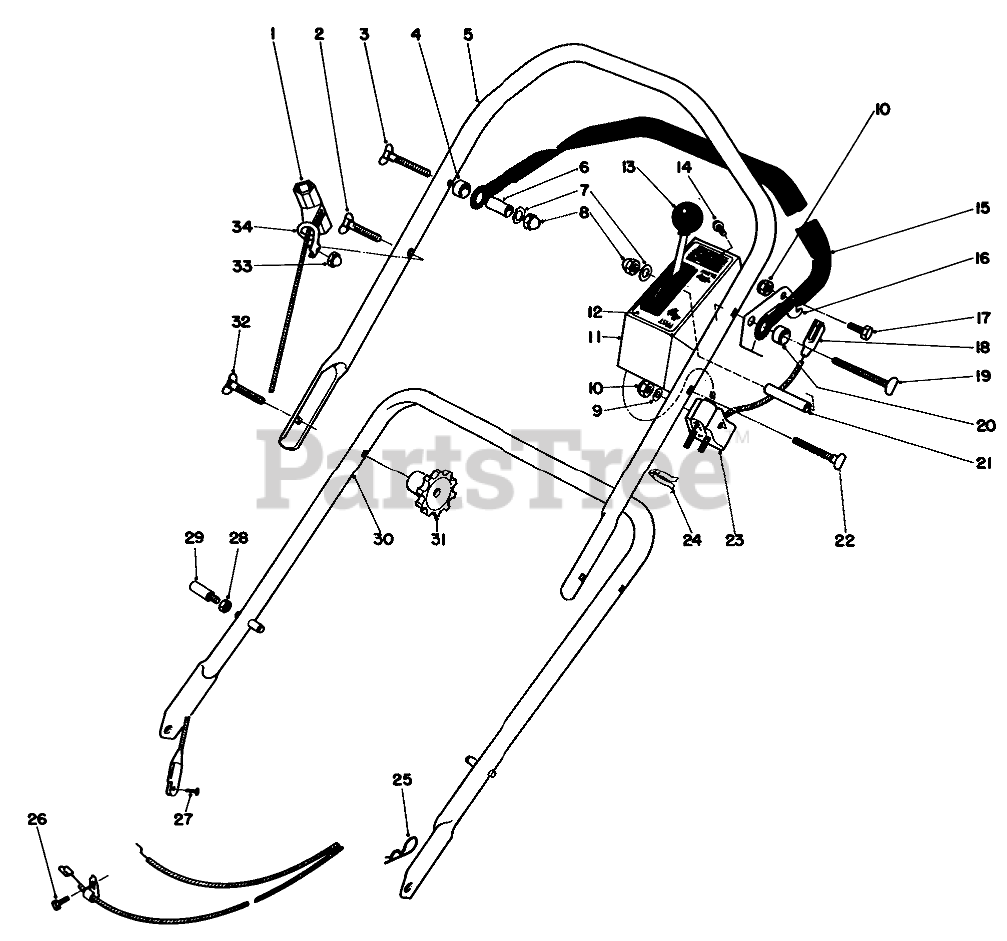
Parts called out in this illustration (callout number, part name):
1	Rope-Starter
2	HANDLE SCREW
3	5/16-18 X 2 HNDLE SCREW
4	SPACER-NYLON
5	UPPER HANDLE
6	Spacer
7	WASHER-FLAT
8	NUT-LOCK, CAP
9	WASHER-FLAT
10	NUT-LOCK, NI
11	Panel-Control (Incl. Ref. #12)
12	Decal-Control Cover
13	SERVICE THROTTLE CONTRO
14	SCREW-HWHTF
15	Control Bar Assembly
16	Lever-Control
17	SCREW-HH
18	BRAKE CABLE
19	5/16-18X3.75 HDLE SCREW
20	Nylon Spacer
21	Spacer
22	SCREW-HANDLE
23	SUPPORT-CABLE
24	BOWDEN CLIP
25	PIN-COTTER, HAIR
26	SCREW-HH
28	Nut
29	HANDLE PIN
30	LOWER HANDLE ASSEMBLY
32	5/16-18 X 2 HNDLE SCREW
33	NUT-CAP
34	Guide
